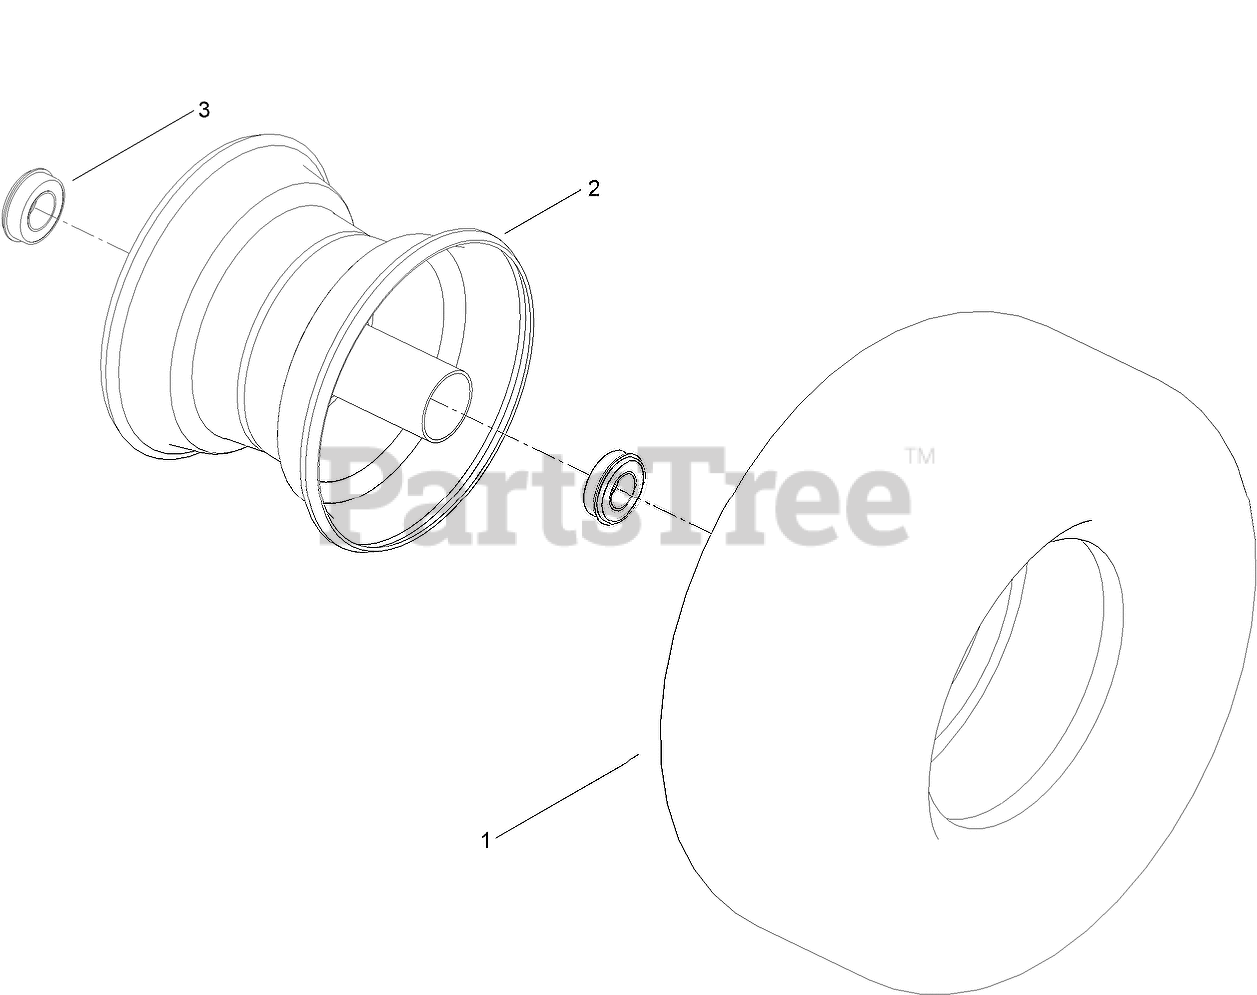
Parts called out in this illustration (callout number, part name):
1	TIRE-13 IN
2	RIM-6"
3	BEARING
